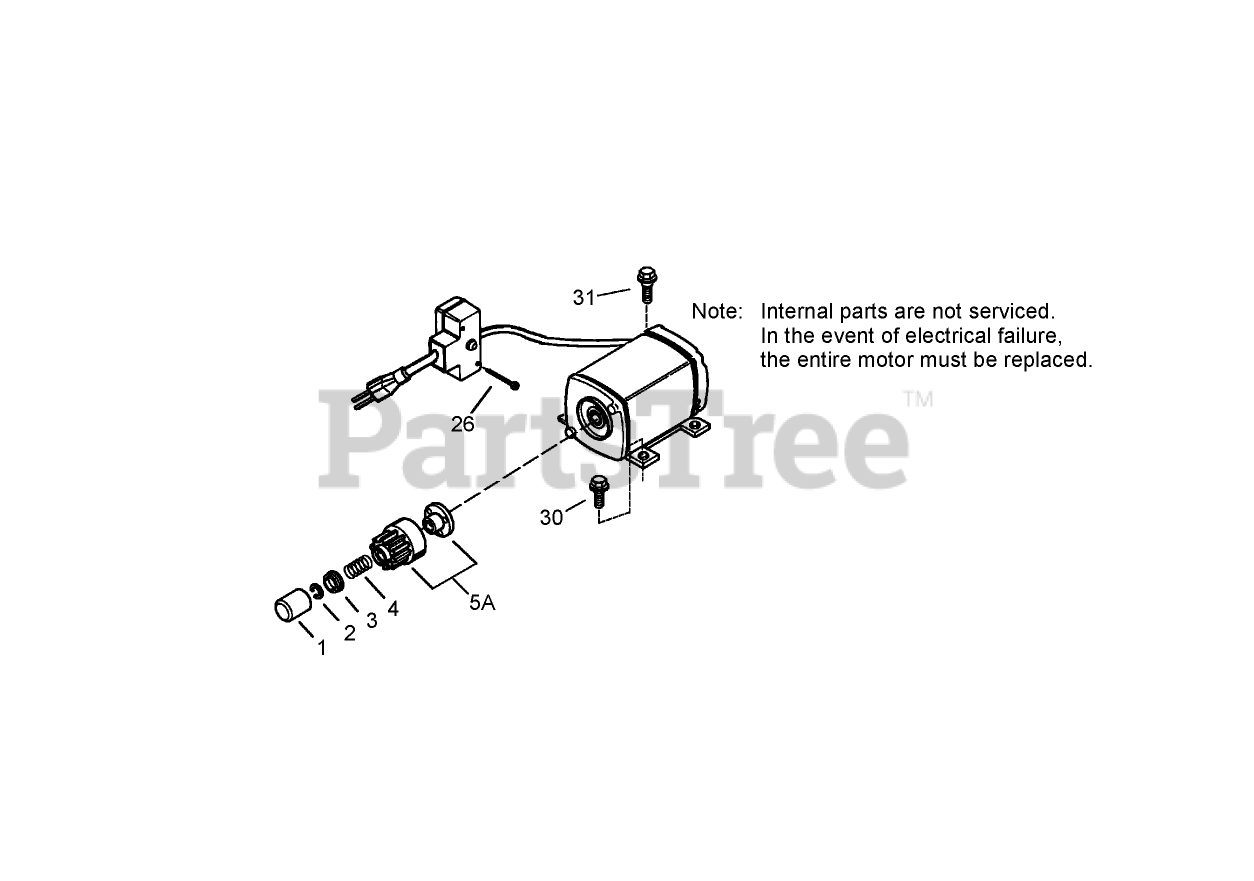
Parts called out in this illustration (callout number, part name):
1	Cover-Dust
2	Ring-Retainer
3	Retainer-Spring
4	Spring-Anti Drift
5A	Gear Nut (Incl. Ref.# 2)
26	Screw
26	Screw (12-16 x 5/8)
30	Screw
31	Screw (1/4-20x1/2)
